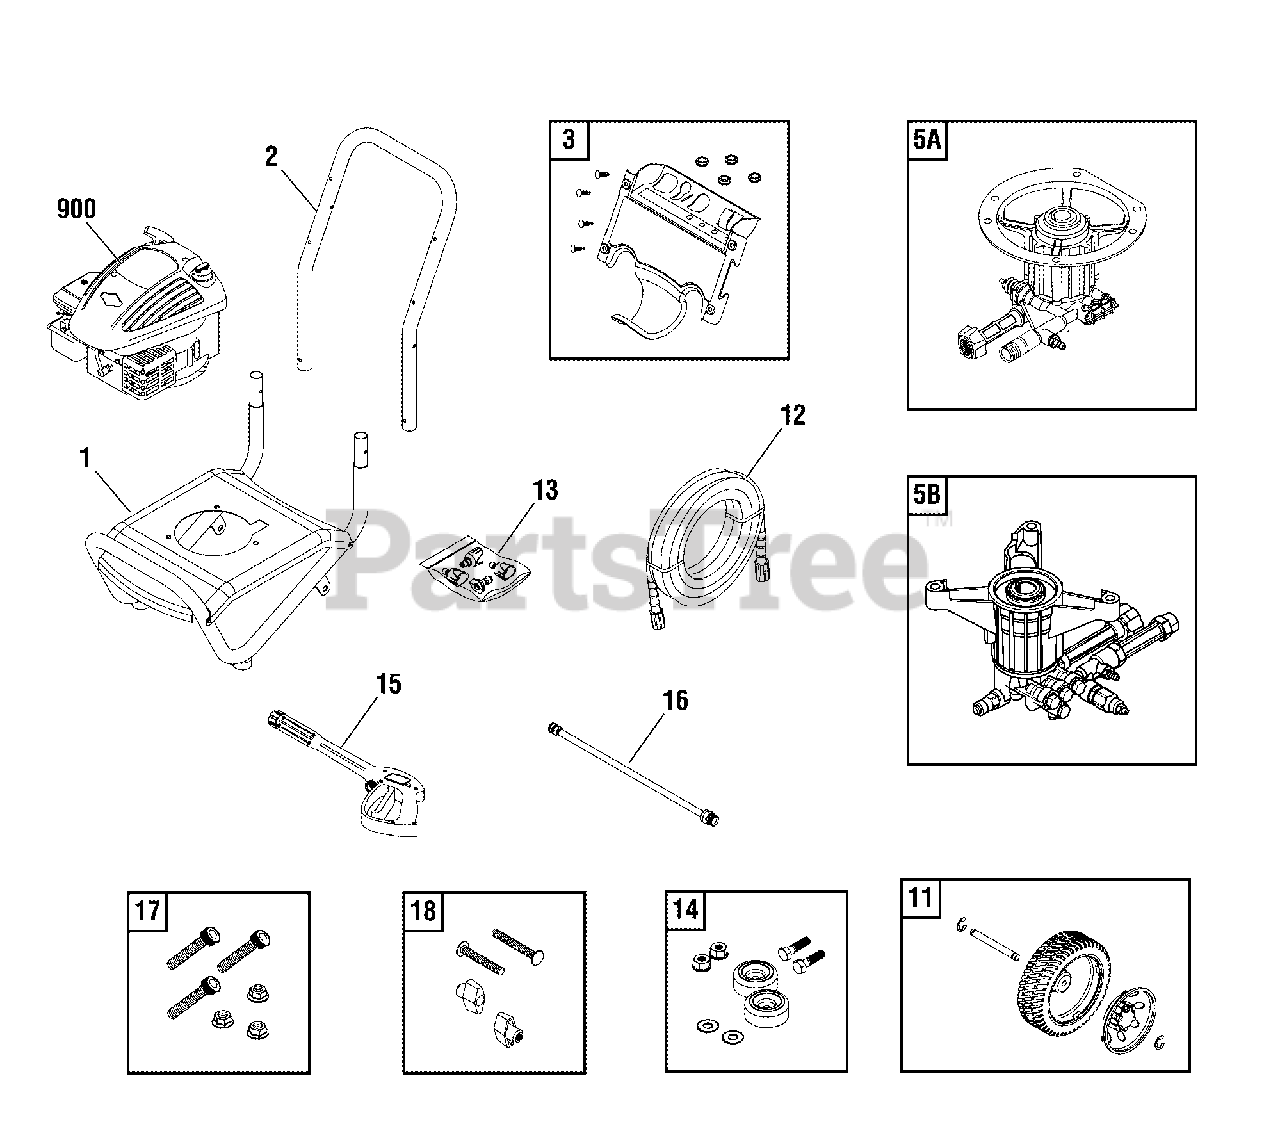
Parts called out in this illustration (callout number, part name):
2	HANDLE
3	BILLBOARD, w/Decals & CLIPS
5A	PUMP
11	KIT, Wheel
12	HOSE
14	KIT, Vibration Mount
15	GUN
16	EXTENSION, QC
17	KIT, Pump Mounting Hardware
18	KIT, Handle Connector
900	* ENGINE
